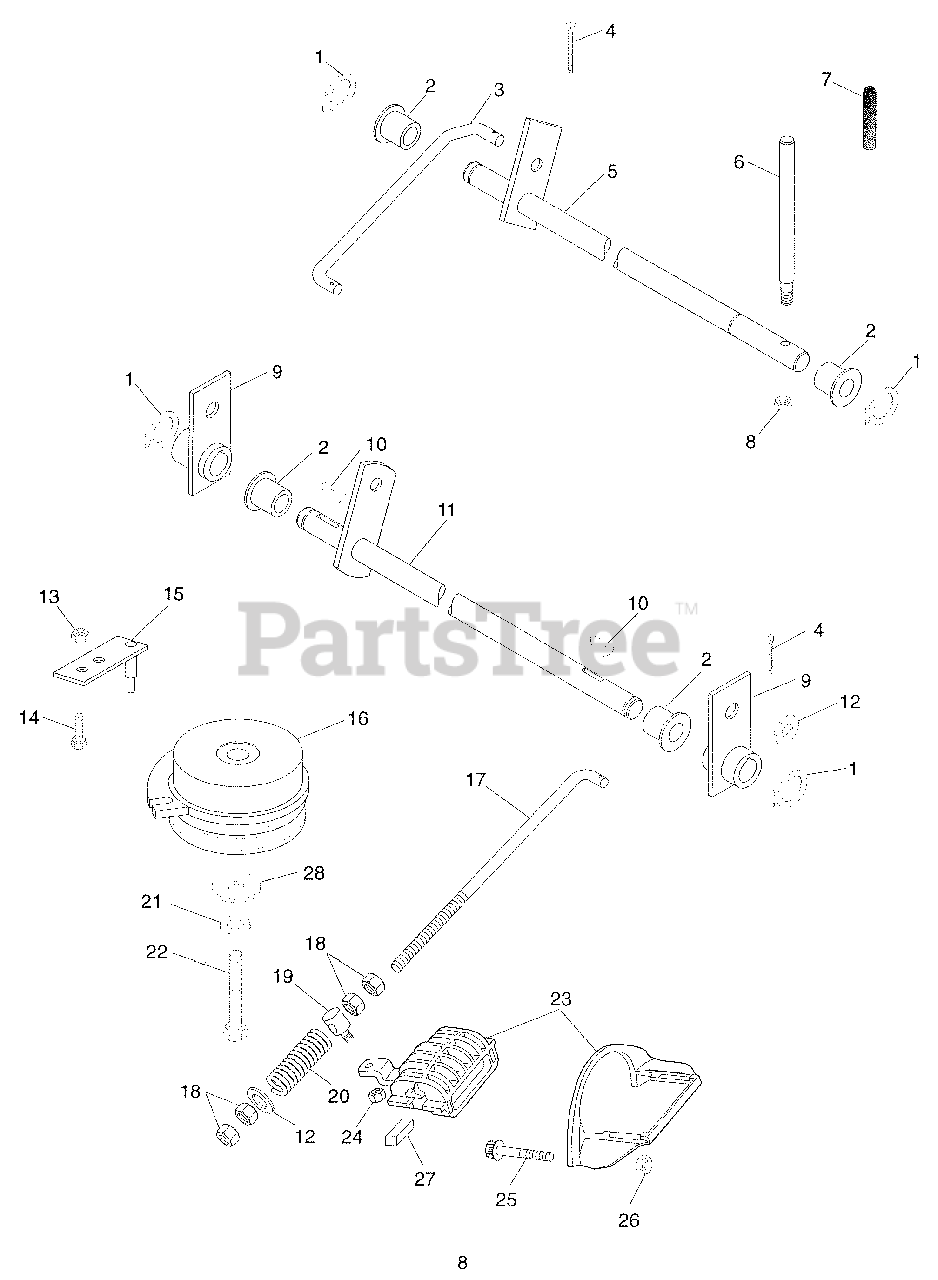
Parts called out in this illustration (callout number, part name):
1	Ring Retaining External .625 X .050
2	Bushing Flange .630 X 1.000 X .625
3	Rod, Brake Actuating
4	Pin Cotter .09- .75
5	Weldment, Brake Actuating Shaft
6	Lever, PTO Actuating
7	Grip, Hand Clutch Lever
8	Nut Locking Nylon .312-18 Grade 2
9	Weldment, Brake Arm RH
10	Key, Woodruff .19 X .75
11	Weldment, Brake Cross Shaft
12	Washer Flat Steel .406 X .812 X .065
13	Nut Locking Nylon .375-16 Grade 2
14	Bolt Hex .38-16 X 1.125
15	Weldment, Elect Clutch Anchor
16	Clutch, Electric
17	Rod, Brake
18	Nut Hex .375-16 Grade 2
19	Pivot, Brake Rod
20	Spring Compression .143 X .710 X 2.00
21	Washer Lock .44 Regular
22	Bolt Hex .44-20 X 3.00 Grade 5 (007, 008, 009, 012, 302)
23	Brake, Disc RH
24	Nut Locking .312-18
25	Screw Flange .50-13 X 2.25 Grade 5
26	Nut Locking Nylon .50-13 Grade 2
27	Pad, Disk Brake
28	Washer Special .469 X 2.000 X .250
